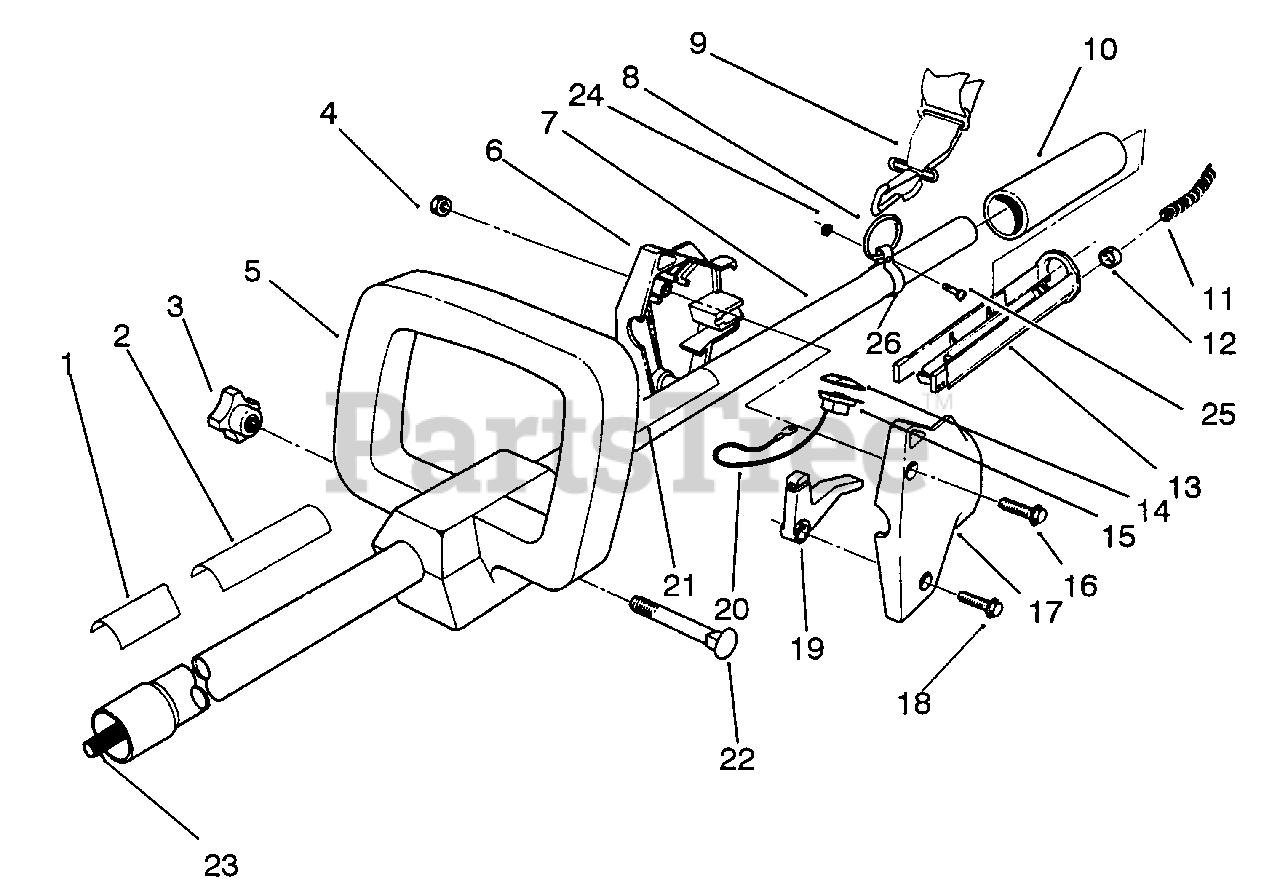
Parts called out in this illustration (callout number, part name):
1	Decal-TC 3100
2	Decal-Danger
3	Knob-Loop Handle
4	Nut-Lock
6	Housing-R.H.
7	Tube Assembly
8	Ring-Harness
9	Harness-Shoulder
11	Cover-Cable
14	Cap-Switch
16	Screw-Hex. Hd.
17	Housing-L.H.
18	Screw-Hex. Hd.
19	Lever-Throttle
20	Wire Assembly
21	Decal-Instructions
22	Bolt-Carriage
23	Shaft-Drive
24	Nut-Lock
26	Clamp-Harness
